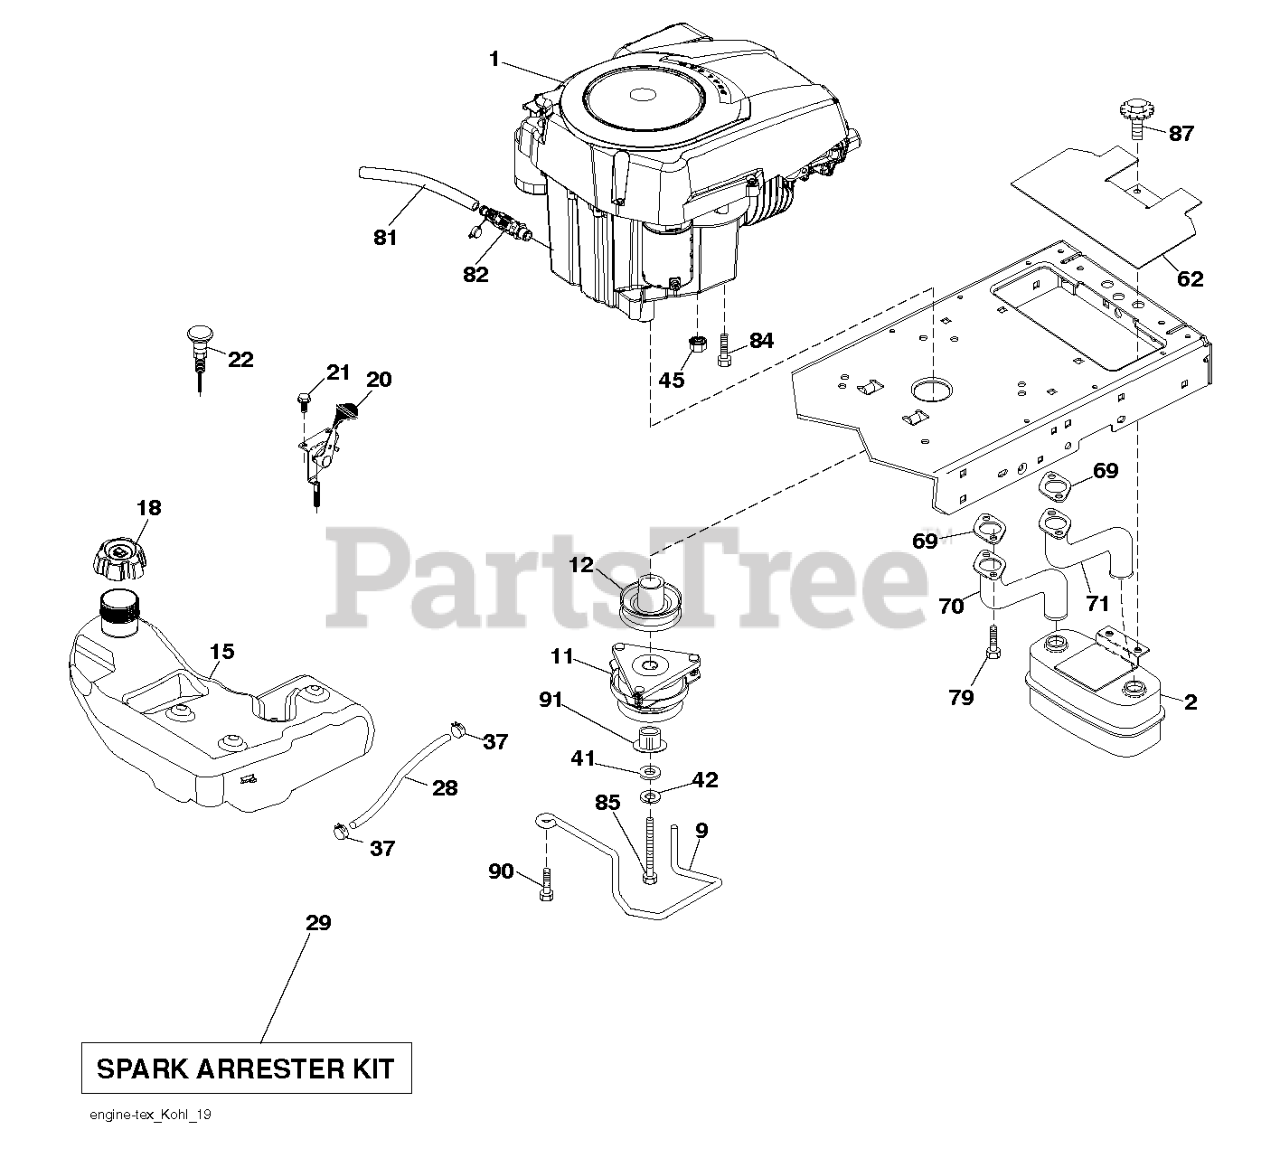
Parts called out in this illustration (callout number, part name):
2	MUFFLER.TWIN.CYL.LOW.TONE
9	KEEPER.BELT.ENGINE.4.2
11	CLUTCH MZ ZTR GT.48/54"1.125"
12	PULLEY ENGINE
15	TANK.FUEL.4GAL
18	RP CAP FUEL
20	THROTTLE CONTROL
21	SCREW.#10 X 0.750.BOS
22	CONTROL.CHOKE.ERGO.PUSH-IN.BLA
28	LINE.FUEL.64"REAR.EMIS
29	KIT.SPARK ARRESTOR 794945 B&S
37	HOSE CLAMP
42	LOCKWASHER
45	NUT
62	SHIELD.HEAT.MUFFLER
69	GASKET.EXHAUST.KOHL.CV18-CV26
70	RP.PIPE-EXHAUST LH
71	RP.PIPE-EXHAUST RH
79	SCREW.SOCKET HD.5/16-1
81	TUBE, DRAIN OIL ASM.
82	VALUE.OIL.DRAIN
84	SCREW 3/8-16X1
85	BOLT HEX 7/16-20 X 3.75 GR. 5
87	BOLT.5/16-18UNCX1.W/SEMS.BLK
90	SCREW 3/8-16X1
91	BUSHING.1.375OD
